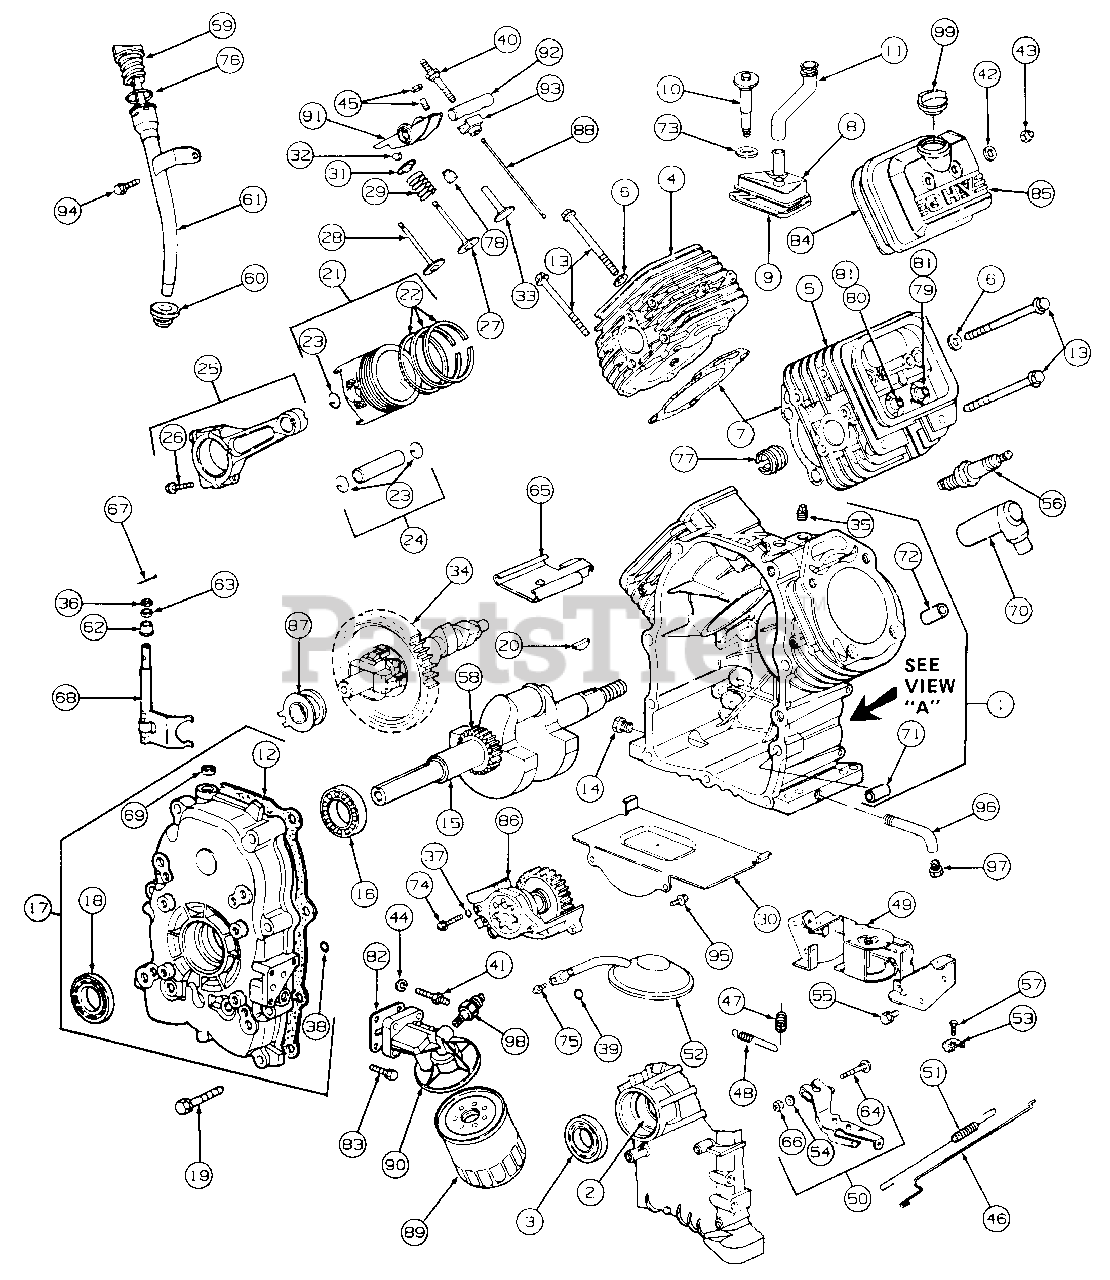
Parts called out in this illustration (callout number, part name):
1	Cylinder Assy
3	Seal, Oil
4	Head, Cylinder (Cylinder #1)
5	Head, Cylinder (Cylinder #2)
7	Gasket, Cylinder Head
8	Breather Assy
9	Gasket, Breather
10	Screw
11	Tube, Breather
12	Gasket, Cover
13	Screw
14	Plug, Oil Drain
15	Crankshaft
16	Bearing, Ball
17	Cover, Crankcase
18	Seal, Oil
19	Screw, Cover
20	Key, Flywheel
21	Piston Assy
22	Ring Set, Piston
23	Lock, Piston Pin
24	Pin Assy, Piston
25	Rod Assy
26	Screw, Rod
27	Valve, Exhaust
28	Valve, Intake
29	Spring, Valve
30	Plate, Windage
31	Retainer, Valve Spring
32	Retainer
33	Valve, Tappet
34	Gear, Cam
35	Plug, Pipe
36	Seal, Governor Shaft
37	O-Ring
39	O-Ring
41	Stud, Adapter
42	Washer
43	Nut, Nylock
44	Lockwasher
45	Screw, Adjustment
46	Link, Governor
47	Spring, Governor
48	Spring, Idle
49	Bracket, Governor
50	Lever Assy
51	Spring, Governor Link
52	Screen, Pick-Up
53	Clamp, Casing
55	Screw, Sems
56	Plug, Spark
57	Screw, Hex Hd
58	Gear, Timing
59	Dipstick
60	Seal
61	Tube, Filler
65	Baffle, Breather
66	Nut, Hex
67	Pin, Cotter
68	Fork, Governor
69	Washer
70	Elbow, Spark Plug
73	Seal, Screw
74	Screw, Sems
75	Screw, Mounting
76	O-Ring
77	Liner, Exhaust Port
78	Seal, Valve Guide
79	Seat, Intake Valve
80	Seat, Exhaust Valve
81	Guide, Valve
82	Gasket, Adapter
83	Screw, Sems
84	Gasket, Valve Cover
85	Cover, Valve LH
86	Oil Pump Assy
87	Slider, Governor
88	Rod,Push
89	Filter, Oil
90	Adapter, Filter
91	Arm, Rocker
94	Screw, Mounting
95	Screw, Sems
96	Pipe, Oil Drain, 3.5 Lg
97	Plug, Oil Drain
98	Switch, Oil Pressure
99	Plug, Oil Fill
